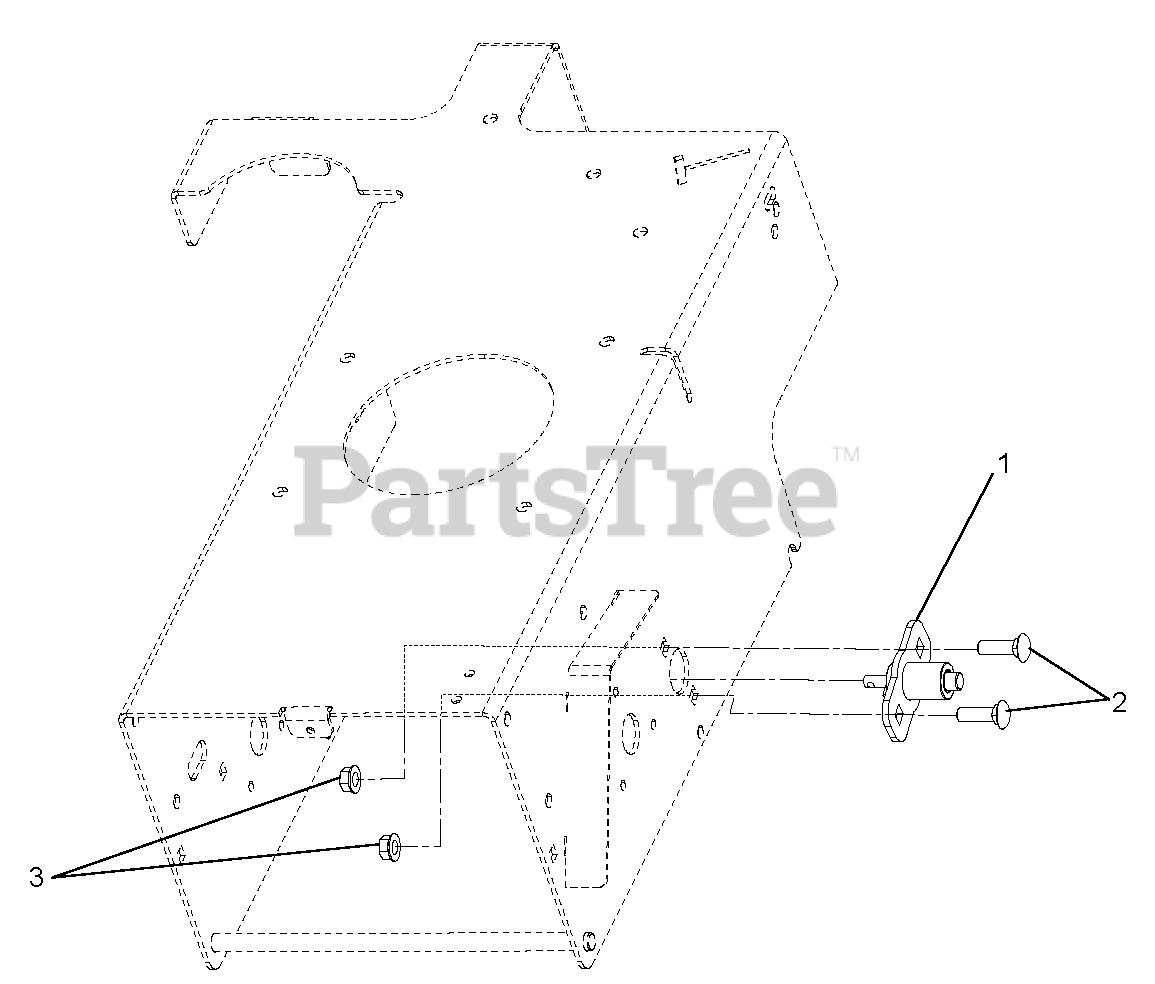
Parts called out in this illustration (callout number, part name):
1	Kit, Pin Brake
2	Bolt, Round Head Square Neck .38-16 x 1.25 Grade 5
3	Nut, Flange .375-16
